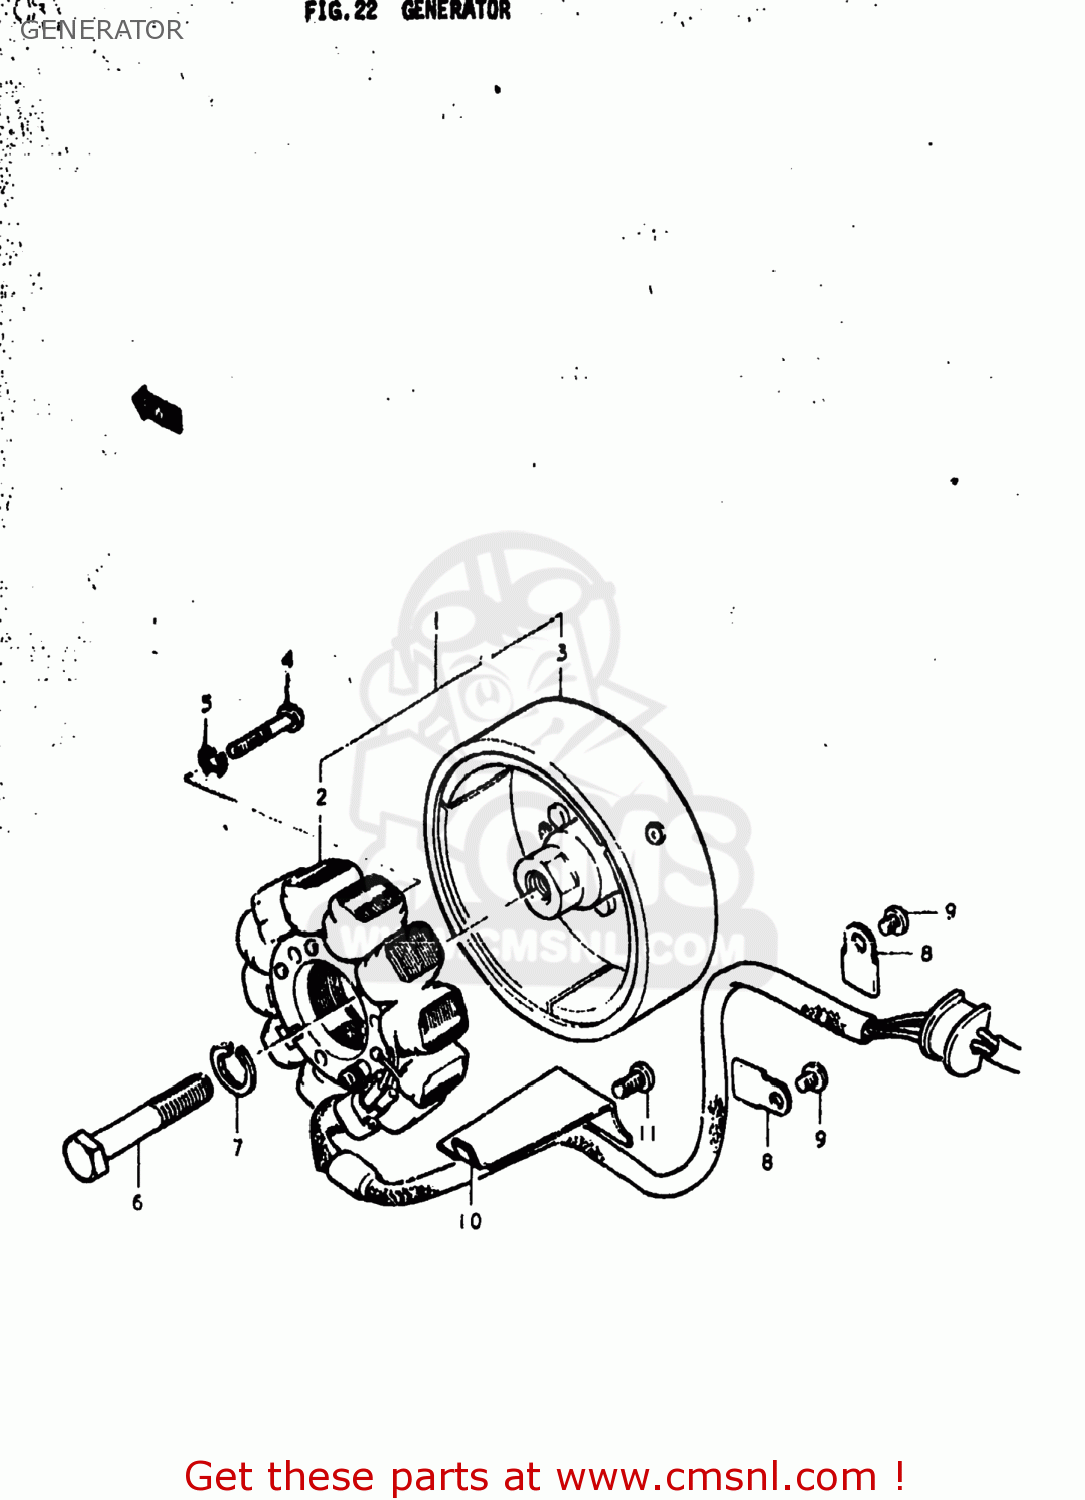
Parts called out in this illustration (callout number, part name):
1	GENERATOR ASSEMBLY
2	STATOR ASSEMBLY
3	ROTOR ASSEMBLY
4	SCREW
5	LOCK WASHER
6	BOLT 12X45
7	WASHER,LOCK 12
8	CLAMP,GENERATOR LEAD WIRE
9	SCREW
10	CLAMP,GENERATOR LEAD WIRE
11	SCREW
